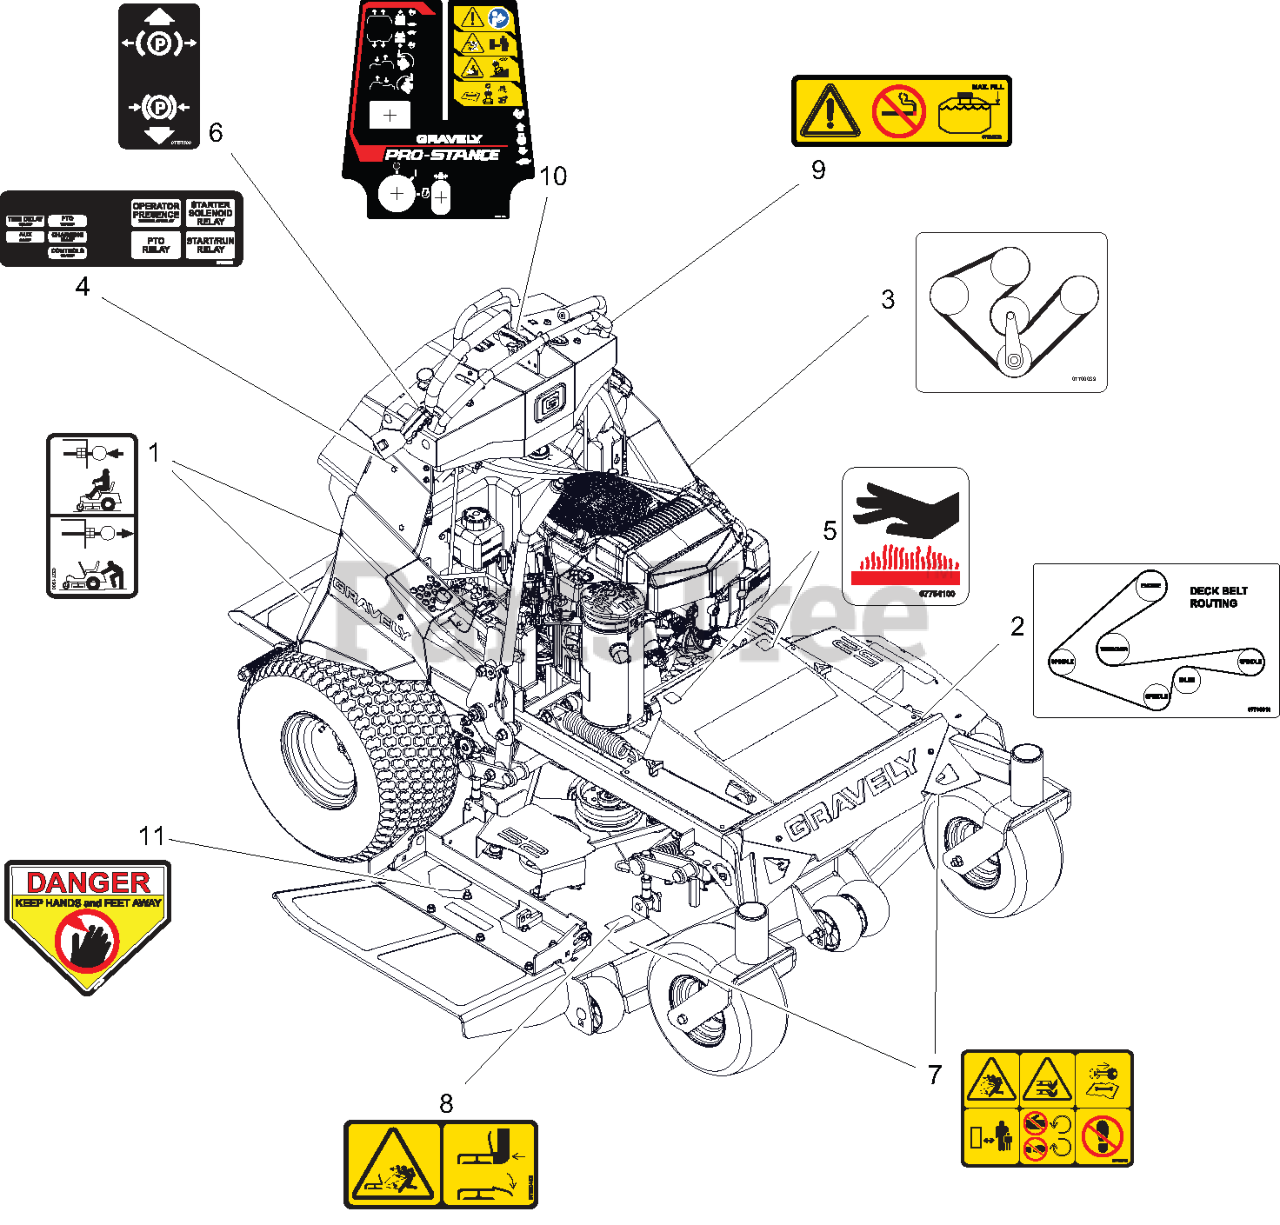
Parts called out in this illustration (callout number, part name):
1	DECAL, TRANSMISSION DISCONNECT
2	DECAL, BELT ROUTING 48/52
3	DECAL, PROSTANCE HYD BELT ROUT
4	DECAL, FUSE BOX
5	DECAL, HOT SURFACE
6	DECAL, PARKING BRAKE LEVER
7	DECAL, SAFETY - MOWER DECK
8	DECAL, SAFETY - DECK GUARDING
9	DECAL, FUEL WARNING
10	DECAL, DASH - PROSTANCE EFI
11	DECAL, DANGER
